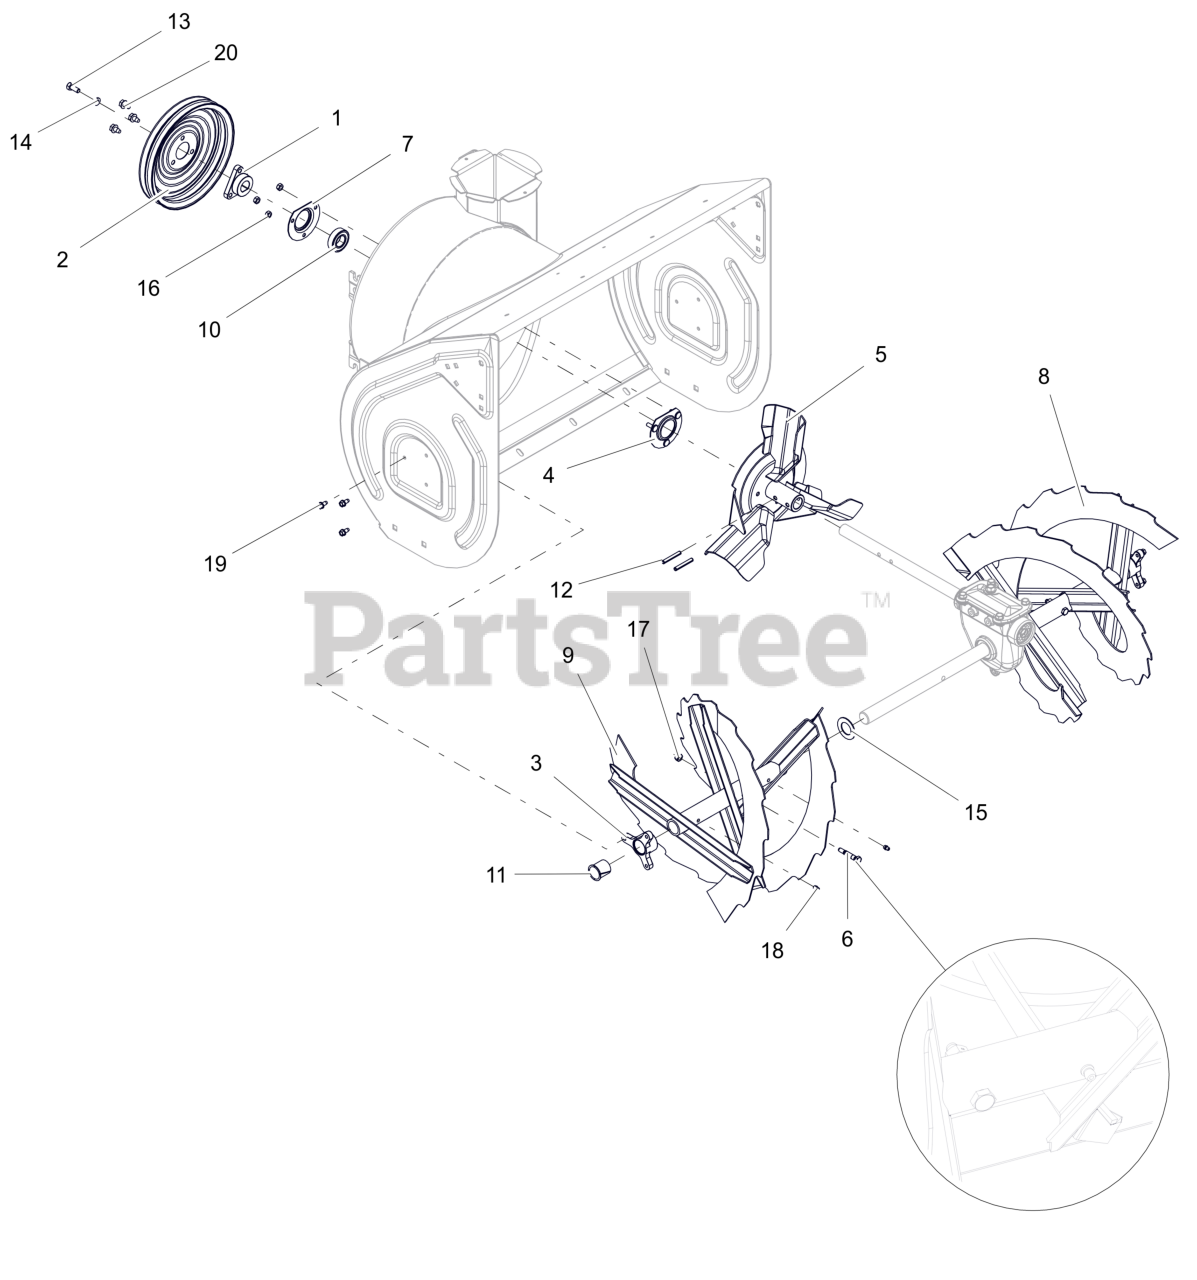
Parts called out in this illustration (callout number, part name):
1	PULLEY HUB, D-BORE .87 PRO
2	PULLEY, SPIN FORM DUAL GROOVE
3	BUSHING, RAKE SHAFT 1"
4	BEARING FLANGE
5	IMPELLER, 3 BLADE-14"
6	SHEAR BOLT SERVICE ASSEMBLY (INCLUDES NUT)
7	BEARING FLANGE
8	RAKE, LH-28"(1 ID X 15.75 OD)
9	RAKE, RH-28"(1 ID X 15.75 OD)
10	BRG-BALL .876X1.75X.50 RSTFP
11	BSHG-FLG SPLIT NYLINER 1.0" HP
12	PIN-ROLL .250X1.75
13	BLT, HEX .31-24X.750 G5 ZCC
14	WSHR, LK-HVY .312X.097 ZCC
15	WSHR- FLT 1.010X1.755X.062 ZCC
16	NUT,LK-CTR .25-20 GA ZCC
17	NUT,LK-CTR .31-18 GA ZCC
18	ZERK,FITTING .25X.125 DRIVE IN
19	SCR-TAP .25-20X.50 HWH ZCC
20	SCR,TAP .312-18X.50 HWH TR ZCC
